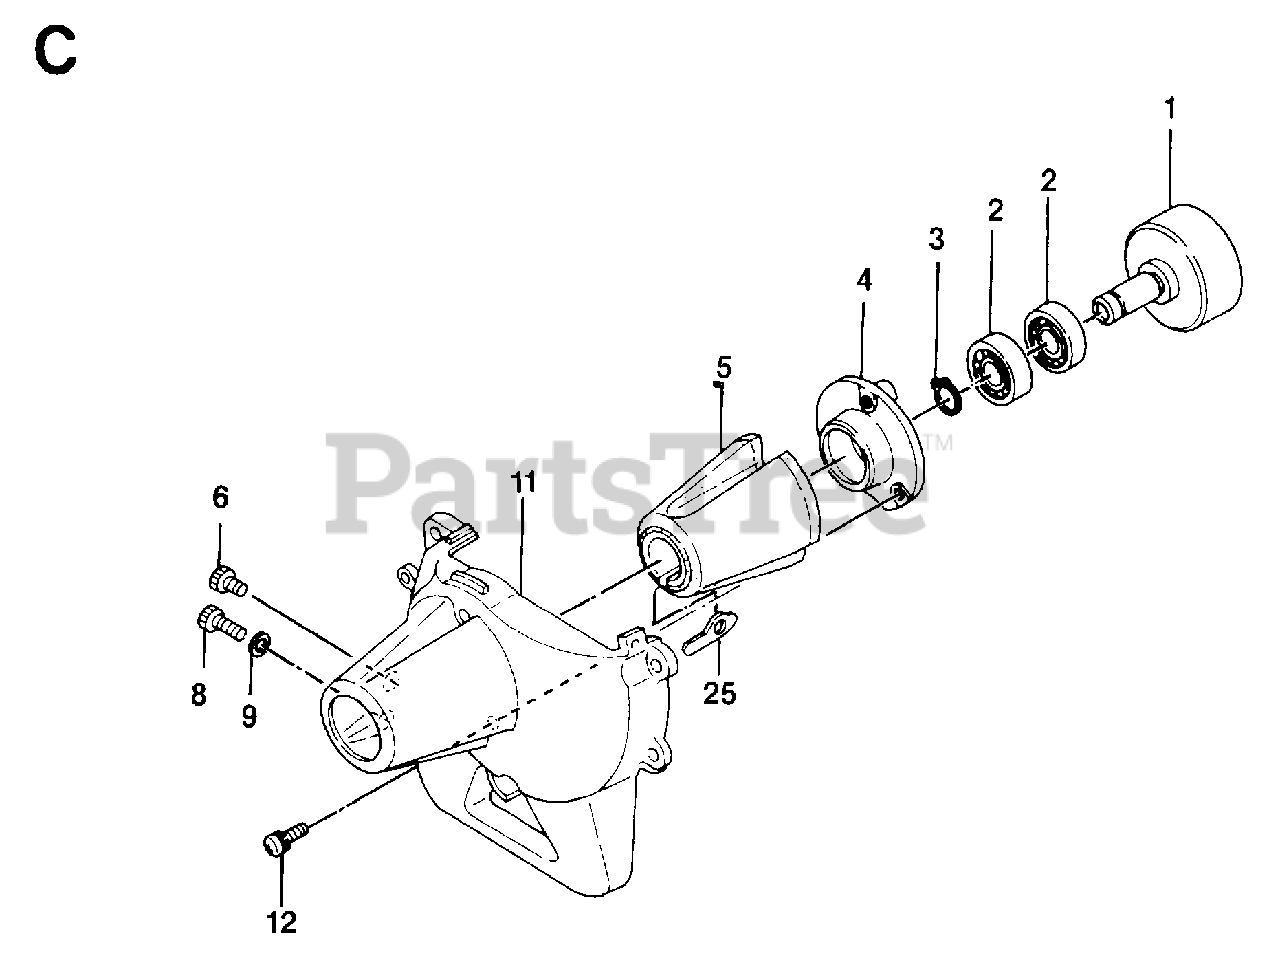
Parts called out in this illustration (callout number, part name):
3	SEEGER CLIP
6	SCREW MC6S 5X10
8	SCREW MC6S 5X20
9	SPRING WASHER
